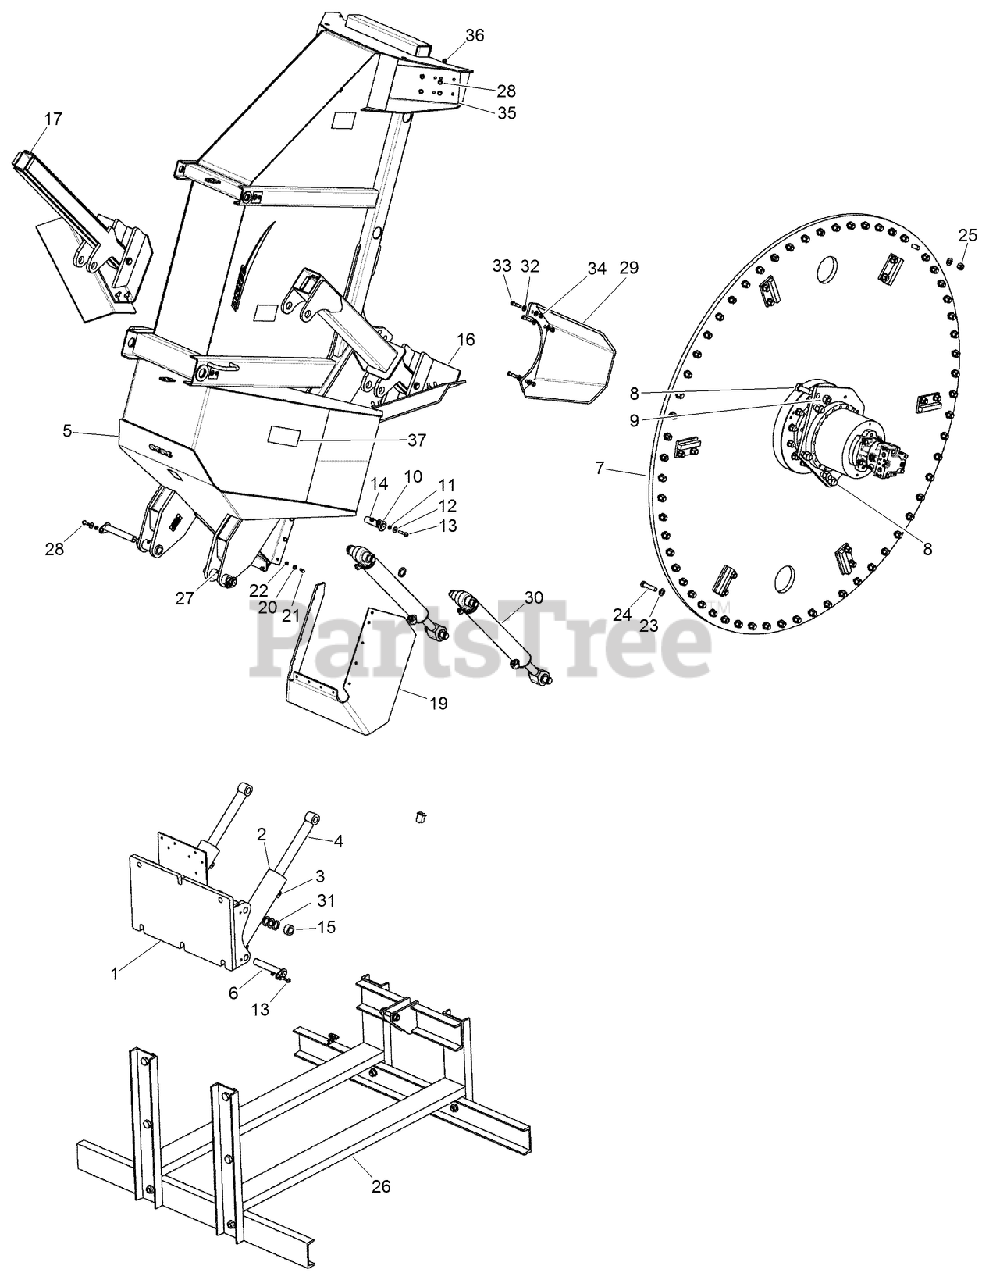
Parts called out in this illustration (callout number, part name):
1	WELDMENT - Rock Wheel Mount
2	CYLINDER - Hydraulic, Base
3	CONNECTOR-Str Thd 3/8, 37FL-ORB 3/8
4	CYLINDER - Hydraulic, Base
5	FRAME WELDMENT - Rock Wheel
6	PIN-PIVOT W/ FLAG
7	WHEEL ASSEMBLY - Motor/Disc/Hardware
10	PIN - Pivot with Flag
13	SCREW-FLANGE
14	NUT-FLANGE, NYLOCK
15	SPACER - Pin
16	ASSEMBLY - Stabilizer, LH
17	ASSEMBLY - Stabilizer, RH
19	SKIRT - Rock Wheel
20	WASHER-0.406 x 0.812 x 0.065 in CST ZND
21	BOLT-hex, 3/8 NC x 1-1/2 inch
22	NUT
24	BOLT - Hex Hd .75 x 3.25 GR8 ZND
25	NUT-Prev Trq 3/4 GRC CAD Direct
26	STAND - Rock Saw
27	FITTING-Lube 1/8-27 Dryseal PTF
28	SCREW-HH
29	WELDMENT - Motor Guard
30	STABILIZER GROUP - Rock Saw
32	WASHER-FLAT
34	NUT-LOCK, HEX
35	PLATE - Adjustable Ejection
36	NUT, METRIC HEX FLANGE - M10, Zinc
37	DECAL GROUP - 46 Rock Saw
